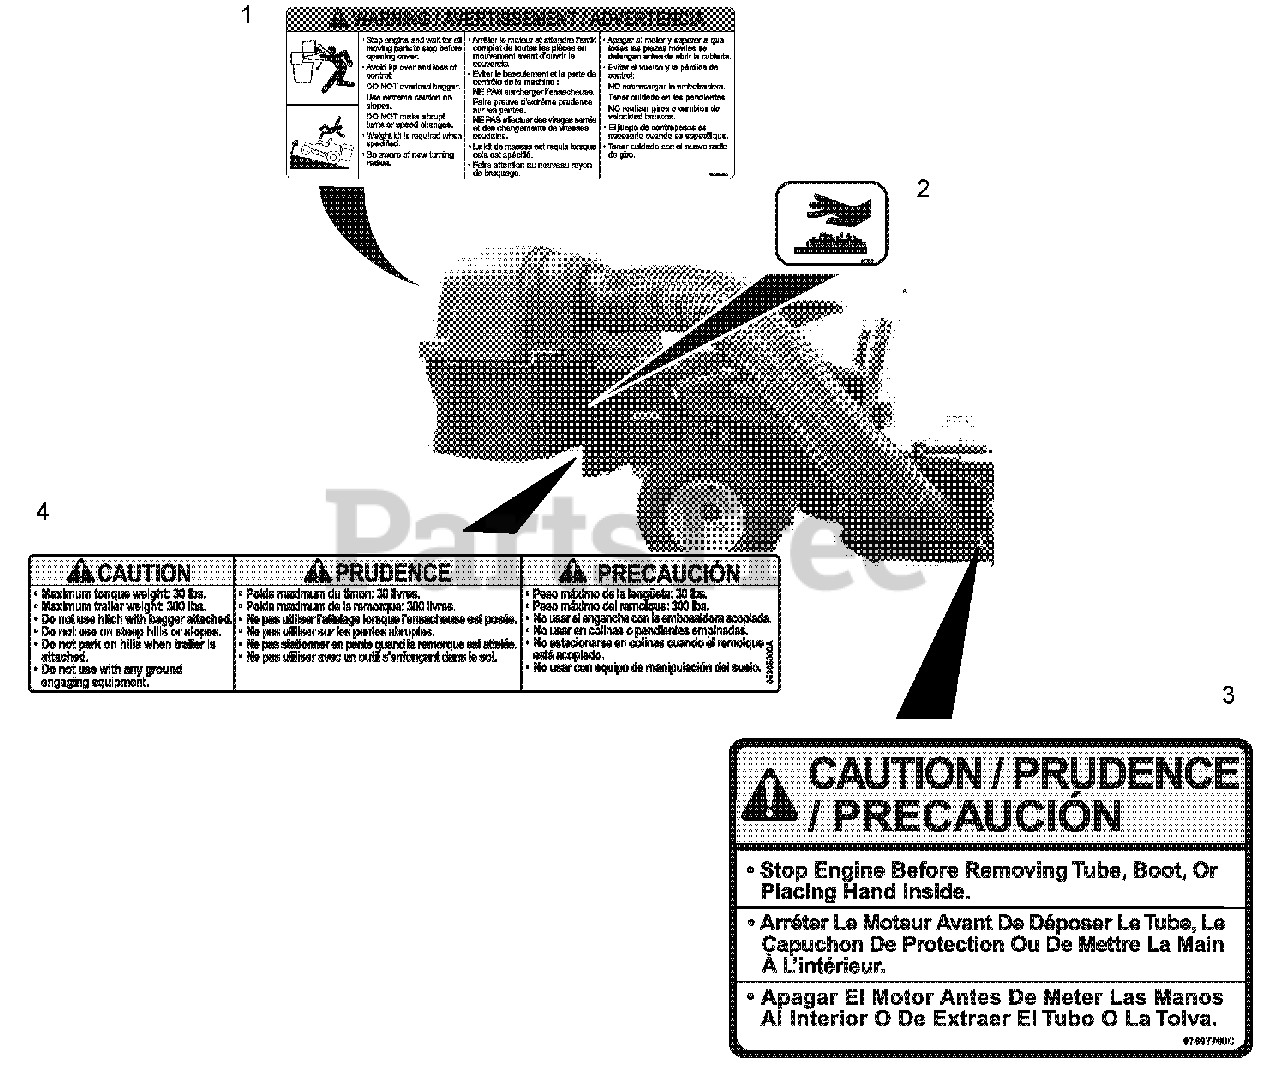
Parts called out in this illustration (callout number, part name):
1	DECAL, BAGGER COVER
2	DECAL, HOT SURFACE
3	DECAL-BOOT CAUTION
4	DECAL, TRAILER HITCH
